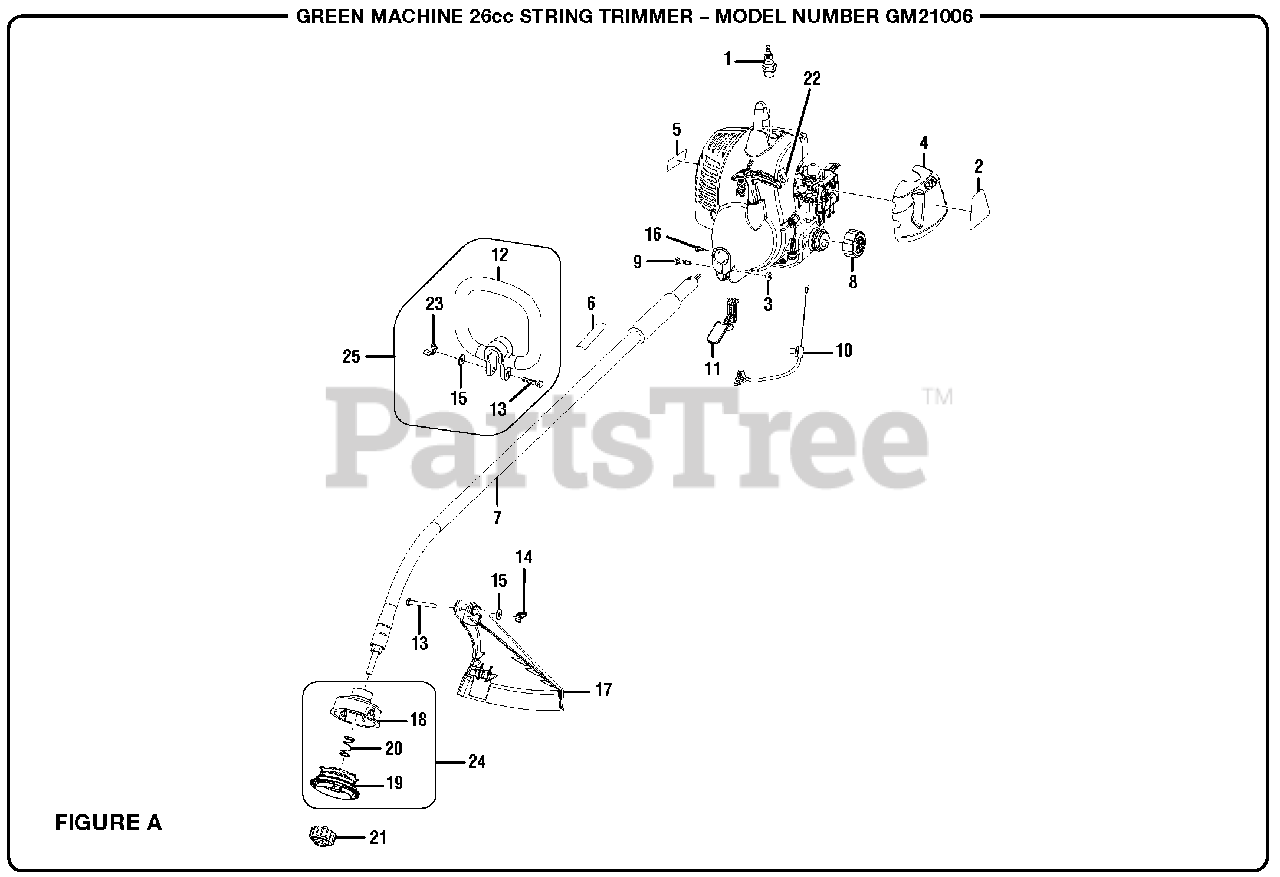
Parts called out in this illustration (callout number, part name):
1	Spark Plug (Champion RCJ6Y)
2	Starting Label
3	Hex Nut (M6)
4	Airbox Cover
5	Combustion Warning Label
6	Warning Label
7	Boom Assembly
9	Bolt (M6 x 20 mm)
10	Throttle Cable
11	Throttle Trigger
13	Bolt (1/4-20 x 40 mm)
14	Wing Nut (1/4-20)
16	Screw (8-16 x 5/16 in)
17	Curved Shaft Grass Deflector
18	String Head Housing
19	Spool
20	Spring
21	Spool Retainer
22	Switch
23	Wing Nut (1/4-20)
24	String Head Assembly
25	Handle Assembly
